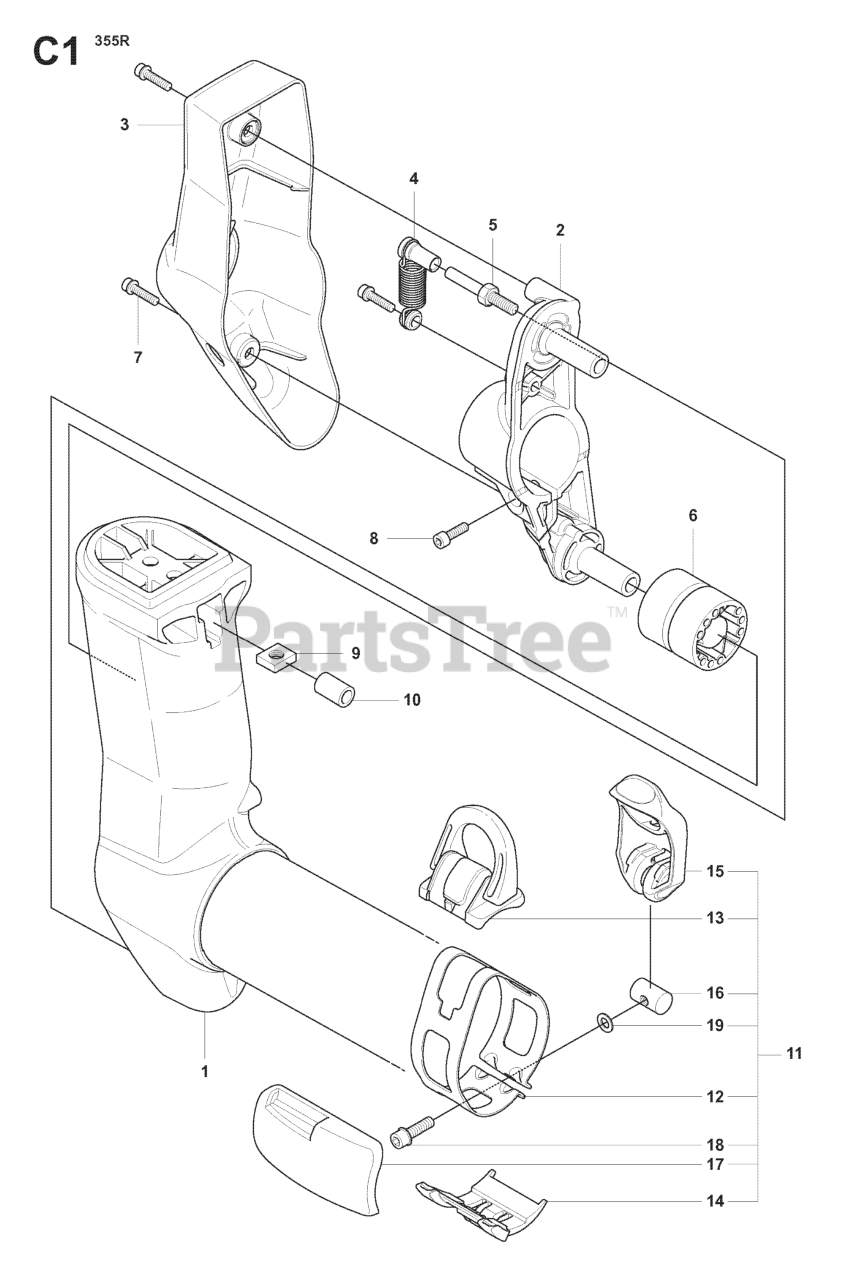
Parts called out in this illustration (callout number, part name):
1	SUSPENSION
4	SPRING
5	PARALLEL PIN
6	ANTIVIBE ELEMENT
7	SCREW IHSCFM
14	GUIDE RAIL
17	WEAR PROTECTION
19	WASHER 5.3X12
